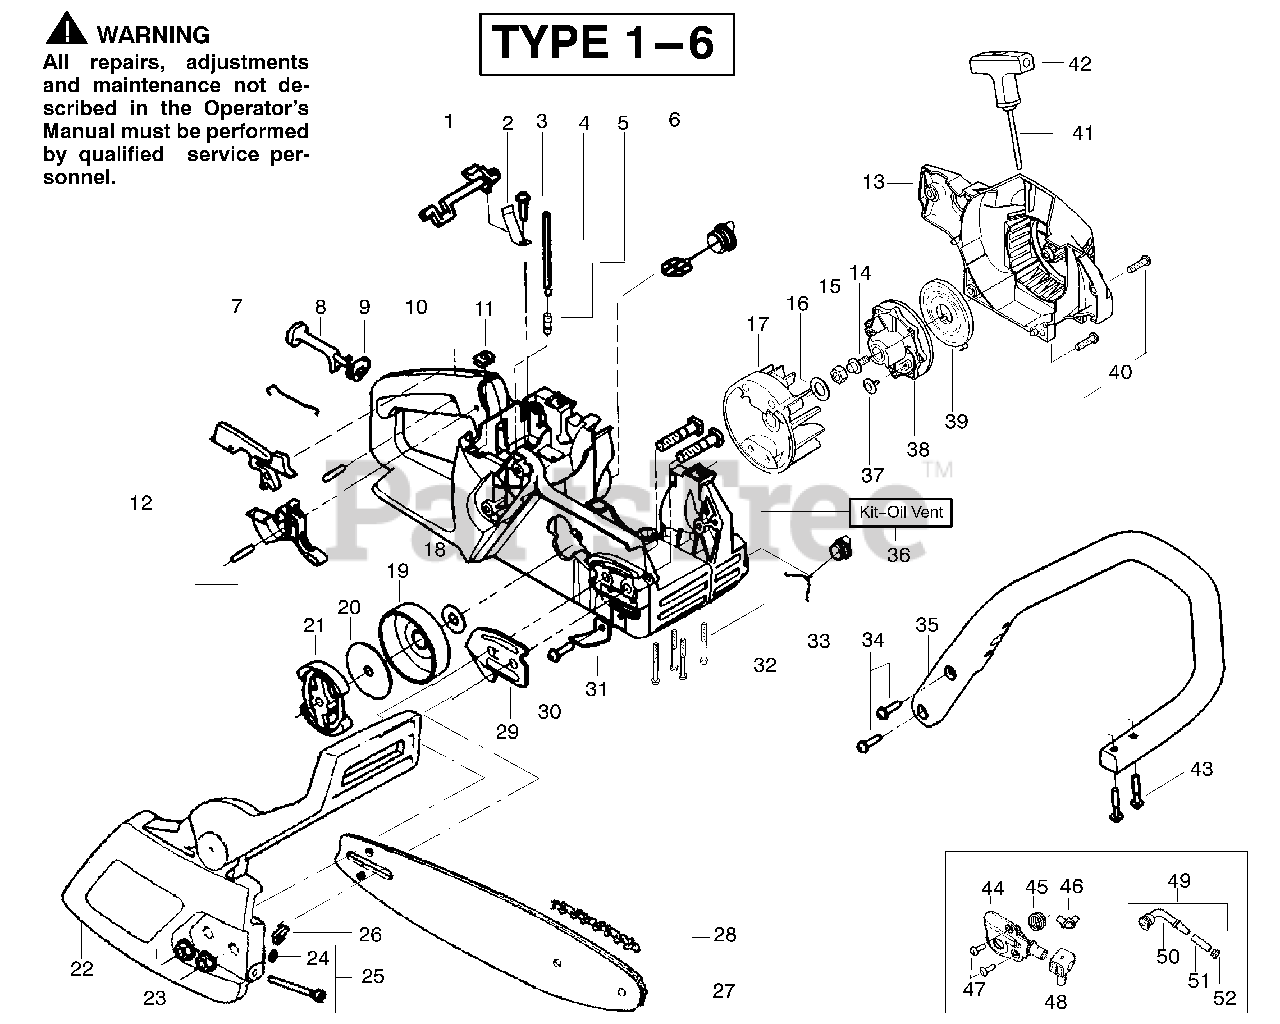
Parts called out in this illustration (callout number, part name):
1	Lever-Switch
2	Spring-Switch
4	Kit-Fuel Line
6	Assy-Fuel Cap
7	Wire-Throttle
8	Lever-Choke
9	Grommet-Choke Knob
10	Kit-Chassis Assy.
11	Nut-Speed
12	Kit-Trigger & Lockout
13	Housing-Fan
15	Nut-Flywheel
16	Washer-Flywheel
17	Assy-Flywheel
18	Washer - Thrust
19	Assy-Drum W/brg.
20	Washer-Clutch
21	Assy. - Clutch
22	Assy-Chain Brake
23	Nut-Bar Mounting
24	Retainer-Bar Adjust
25	Kit-Bar Adjust
26	Pin-Bar Adjust
28	Chain-14"
29	Plate-Bar Mounting
31	Chain Catcher
33	Assy-Oil Cap
35	Handle-Front
36	Kit-Oil Vent
38	Pulley-Starter
39	Spring-Starter
41	Kit-Rope
42	Handle-Starter
44	Kit-Oil Pump
45	Gear-Worm Spring
46	Elbow-Oil Pickup
48	Seal Block
49	Assy-Oil-Pickup
50	Pickup-Oiler
51	Filter-Oil
52	Plug-Oil Filter
